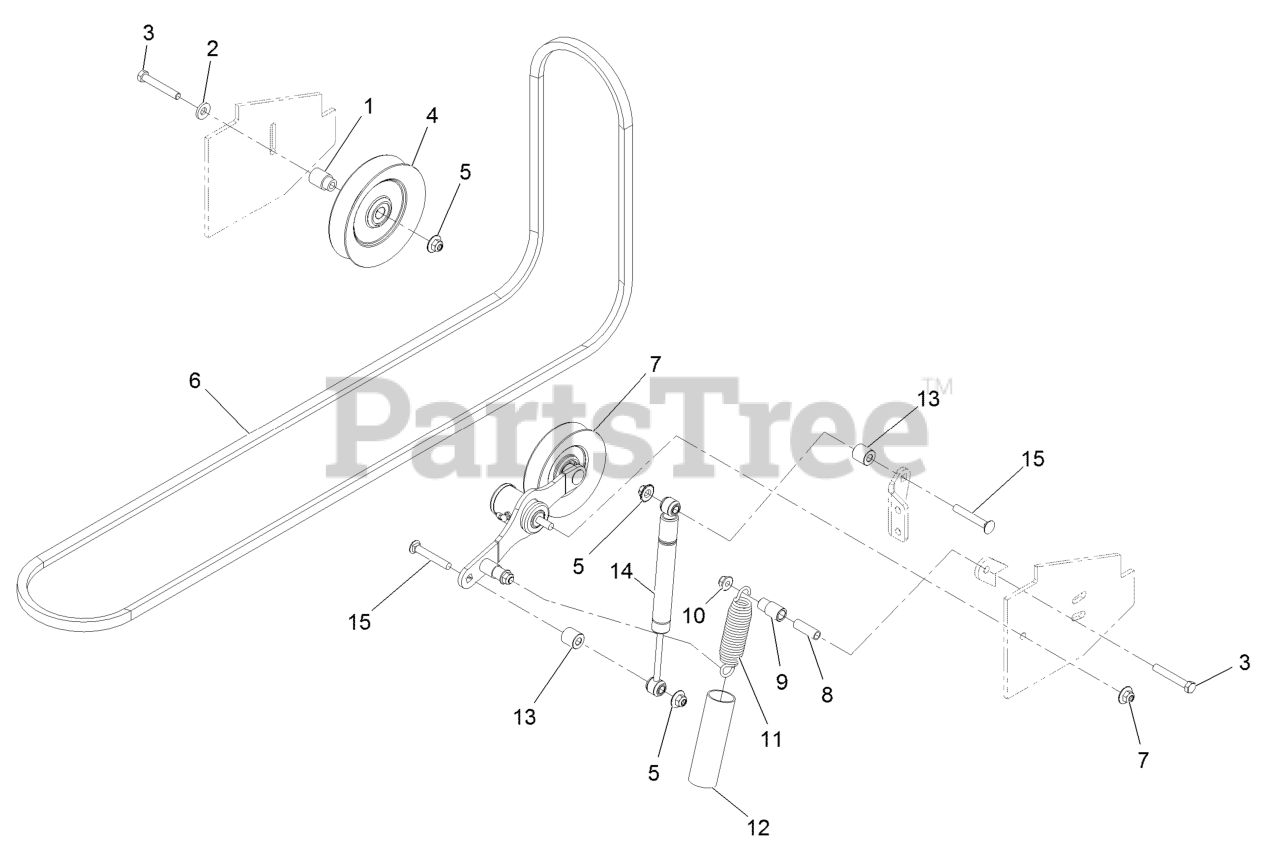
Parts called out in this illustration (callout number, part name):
1	BUSHING-IDLER
2	WASHER-BELLEVILLE
3	BOLT-CARR
4	PULLEY-IDLER
5	Nut-Nyloc 3/8-16 Flg
6	BELT,B 123.2
7	ASM-TTNR ARM W/PULLEY
9	BUSHING,PLASTIC
10	NUT-HF, NI
11	SPRING-EXTENSION
12	DAMPENER,SPRING
13	SPACER-.39IDX.88ODX.88L
14	DAMPER-MULE BELT DRIVE
15	SCREW-CARR
